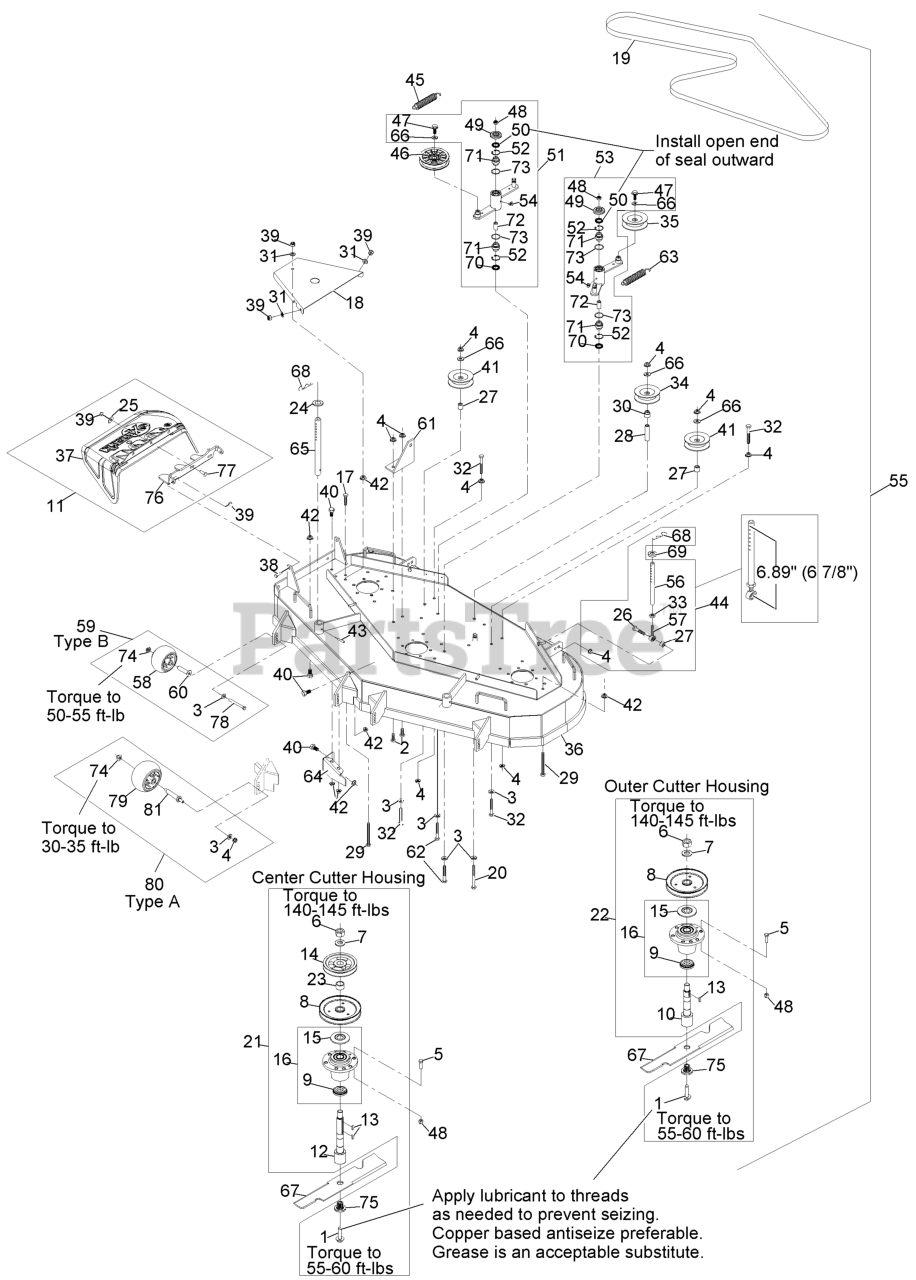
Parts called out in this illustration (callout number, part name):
1	SCREW,SEMS 1/2-20 X 2.19
2	SCREW-HH
3	WASHER-BELLEVILLE
4	NUT-HHF, WHIZ
5	SCREW-HH
8	SHEAVE,BLADE DRIVE 6.30
9	SPACER-GUARD, BOTTOM
10	KIT, SPLINED SPINDLE 103-
11	ASM,FMD DISCHARGE CHUTE
12	KIT, SPLINED SPINDLE 103-
14	SHEAVE,MOWER DRIVE
15	GUARD-BEARING, TOP
16	KIT, CUTTER HOUSING
17	SCREW-HH
18	SHIELD,BELT SIDE FMD524
19	BELT,BLADE DRIVE FMD524
20	SCREW-HH
21	ASM,CUTTER HSG FMD524 CTR
22	ASM, CUTTER HSG COMPLETE
23	SPACER,TUBE
24	SPACER-DECK SUPPORT
25	WASHER-FLAT
26	SCREW-HH
28	SPACER-ANCHOR, CLUTCH
29	BOLT,TAP HH
30	BUSHING,IDLER
31	WASHER-FLAT
32	BOLT-CARR
33	NUT-HJ
34	PULLEY-IDLER
35	PULLEY-IDLER
36	ASM, DECK W/ DECALS FMD52
37	CHUTE,DISCHARGE
38	SCREW-HH
39	NUT-LOCK, NI
40	SCREW-HH
41	IDLER,PULLEY
44	KIT,SUPPORT LINK W/PIN
45	SPRING-EXTENSION
46	PULLEY-IDLER, FLAT
47	SCREW-HHF
48	NUT-LOCK, NI
49	GUARD-TOP
50	SEAL-LIP, SINGLE
51	KIT, IDLER ARM W/BEARINGS
52	RING-SNAP
53	KIT, IDLER ARM W/BEARINGS
54	FITTING-GREASE, 90 DEG
55	Asm, Complete Deck
56	LINK,SUPPORT
57	BALLJOINT
58	ROLLER-SCALP, ANTI
59	KIT, ANTI-SCALP ROLLER
60	AXLE, ROLLER
61	BRACKET,SPRING ANCHOR
62	SCREW-HH
63	SPRING-EXTENSION
64	BAFFLE,DISCHARGE
65	ROD,DECK SUPPORT
66	WASHER-FLAT
68	PIN,HAIR COTTER
70	SEAL-LIP, DOUBLE
71	BEARING-SPHERICAL
72	BUSHING-LEVER, LIFT
74	Nut-Nyloc 3/8-16 Flg
75	BUSHING,SPLINED
76	BRACKET, DISCHARGE CHUTE
77	SCREW-CARR
78	SCREW-HH 3/8-16 X 3 3/4 GR 8
79	ROLLER-SCALP, ANTI
